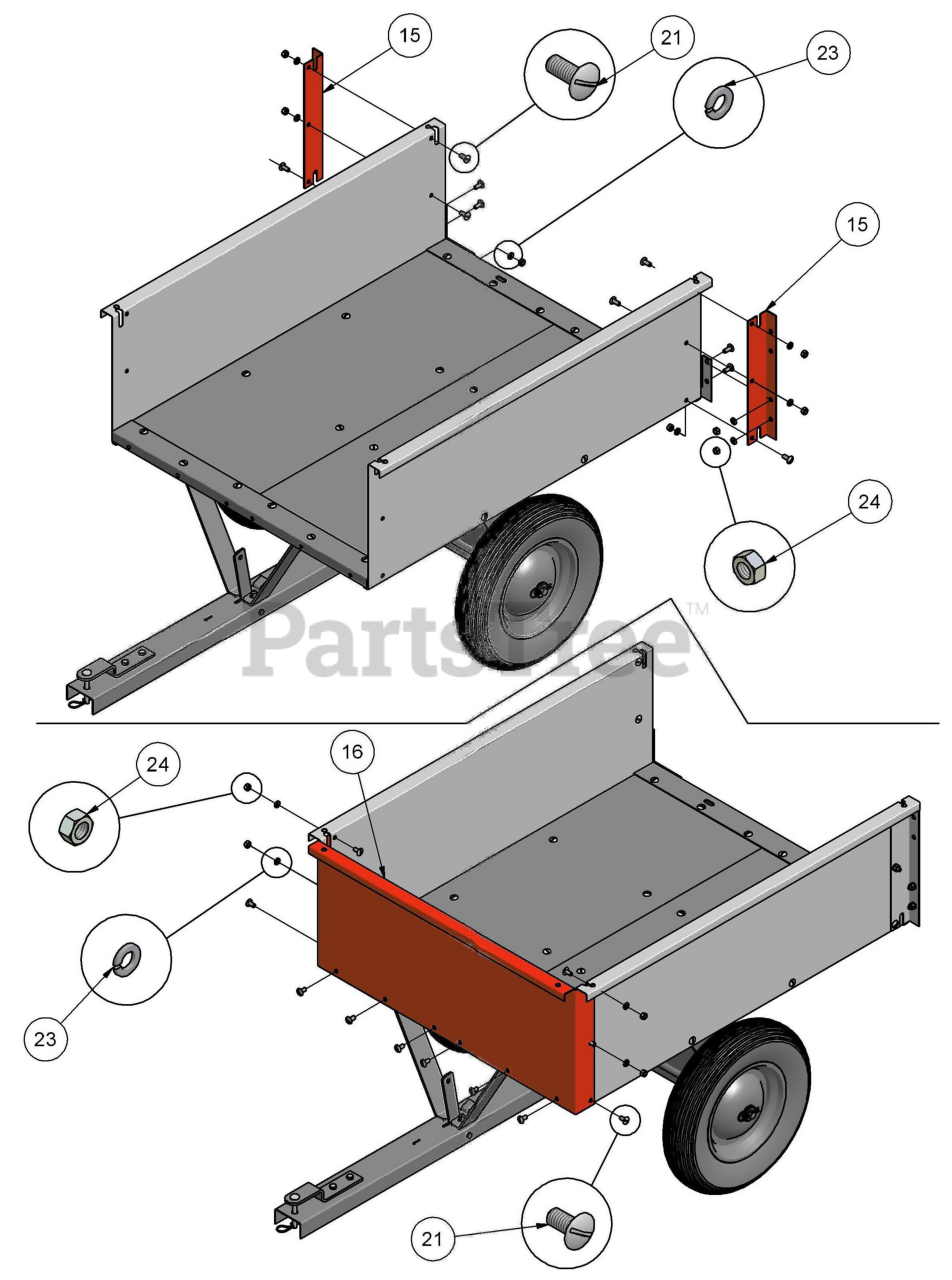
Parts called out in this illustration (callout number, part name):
15	REAR CORNER BRACE
16	FRONT PANEL
21	M8 X 16 TRUSS HEAD BOLT
23	8MM LOCK WASHER
24	8MM HEX NUT
